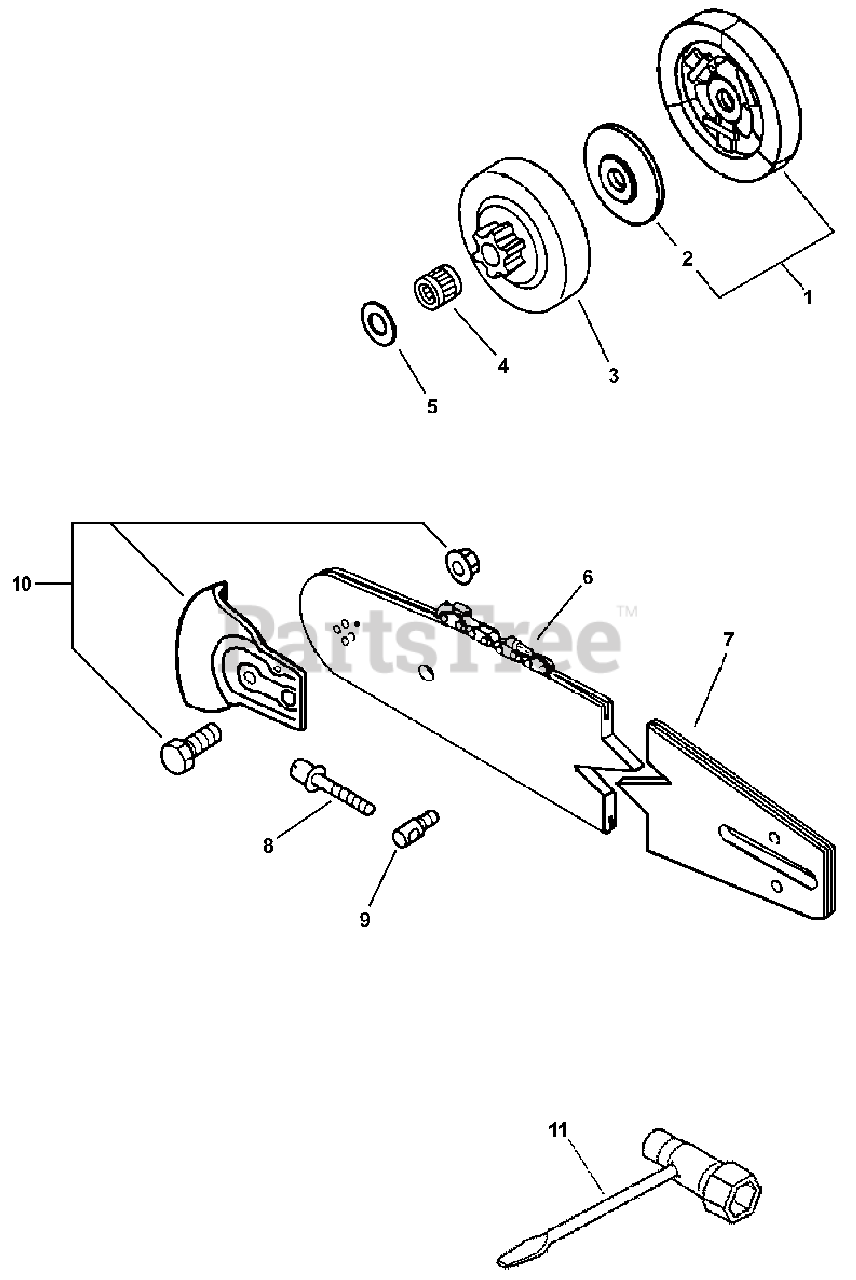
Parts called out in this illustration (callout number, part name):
1	CLUTCH ASSY
2	PLATE, CLUTCH
3	DRUM, CLUTCH
4	BEARING, NEEDLE
6	SAW CHAIN - 12" (30cm)
6	SAW CHAIN - 14" (35cm)
6	SAW CHAIN - 16" (40cm)
7	GUIDE BAR - 12" (30cm)
7	GUIDE BAR - 14" (35cm)
7	GUIDE BAR - 16" (40cm)
8	SCREW, TENSIONER
9	TENSIONER, CHAIN
10	KICK GUARD KIT
